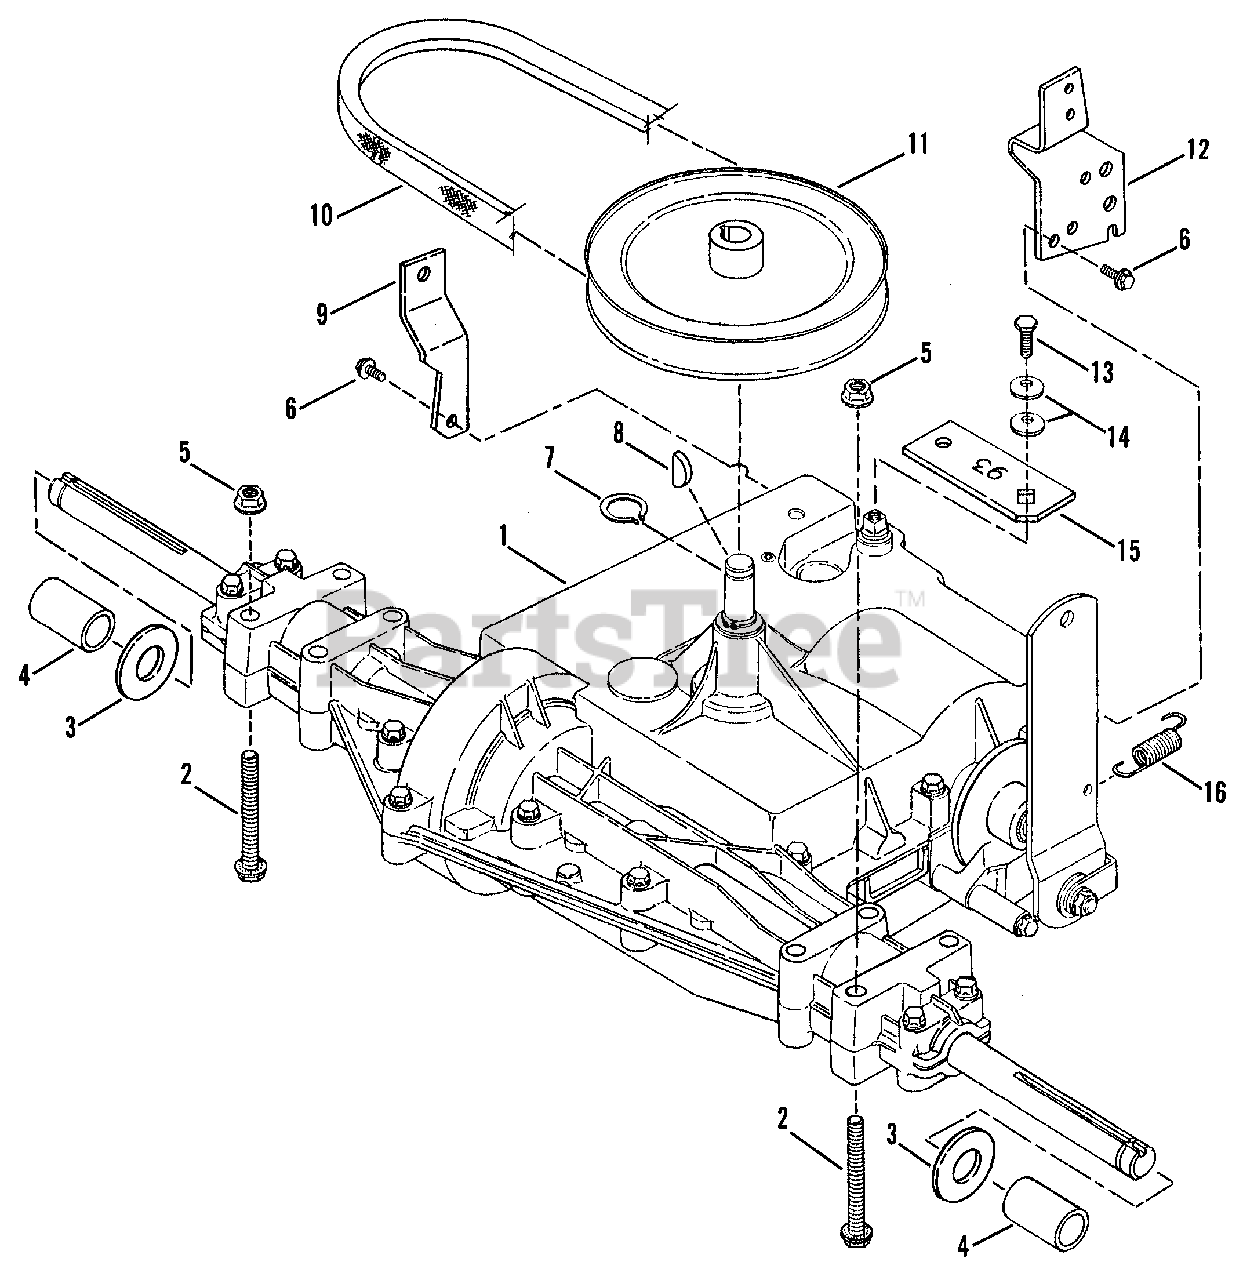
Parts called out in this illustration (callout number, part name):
1	TRANSAXLE, Peerless Model 930, 6-Speed
2	BOLT, 5/16-18 x 2 1/4" Hex Flange Lock
3	WASHER, Flat
5	NUT, 5/16-18 Hex Flange Lock
6	SCREW, 5/16-18 x 5/8" Hex Washer Head, Self-Tapping
7	RING, Retaining
8	KEY, Woodruff, 3/16 x 3/4", No. 9
9	BRACKET, Torque
10	BELT, P930, Traction Drive, 97.75" EL
11	PULLEY, Drive
12	BRACKET, Axle/Spool
13	BOLT, 1/4-28 x 5/8" Hex Head
14	WASHER, Bellville
15	ARM, Shift Link Lever
16	SPRING, Brake Return
